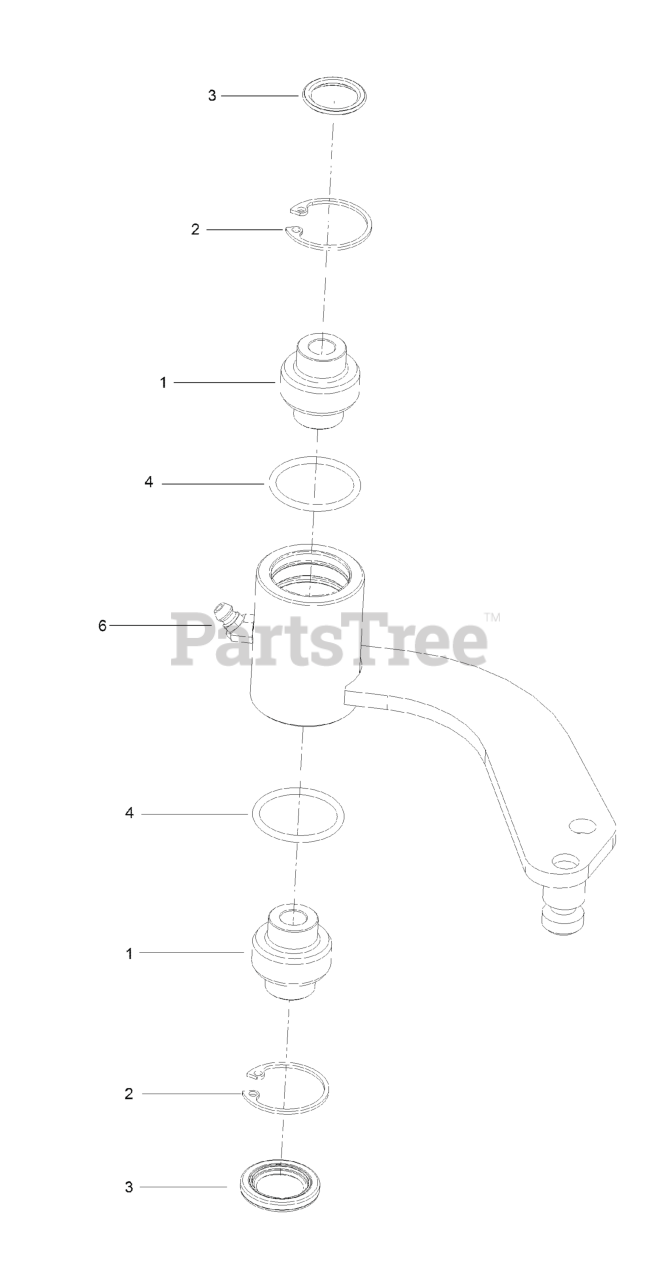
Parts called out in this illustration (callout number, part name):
1	BEARING-SPHERICAL
2	RING-SNAP
3	SEAL-LIP, SINGLE
6	FITTING-LUBE, 45 DEG
